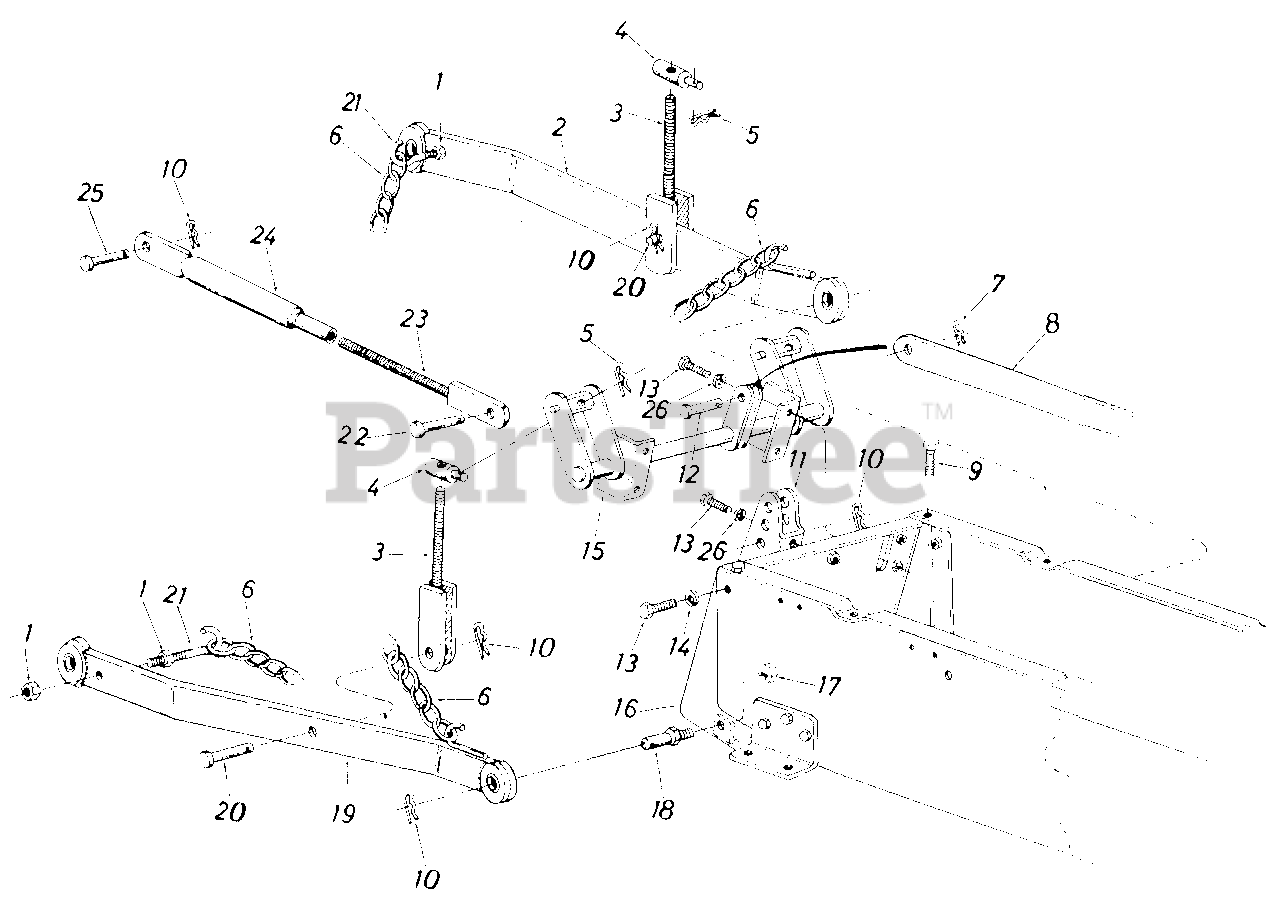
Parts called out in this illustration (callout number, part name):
1	Hex Cent. L-Nut 7/16-14 Thd.
2	Draft Bar Ass'y.-L.H.
3	Clevis Screw Ass'y.
4	Clevis Pin
5	Hitch Pin Clip
6	Chain 20 Links
7	Cotter Pin 1/8" Dia. x 1.25" Lg.
10	Hairpin Cotter
12	Clevis Pin
13	Hex Scr. 3/8-16 x .75" Lg.
14	L-Wash. 3/8" Scr. H.D.
18	Link Clevis Pin
19	Draft Bar Ass'y.-R.H.
20	Clevis Pin .63 Dia. x 1.66" Lg.
21	Hitch Chain Hook
22	Clevis Pin .63 Dia. x 2.4" Lg.
23	Clevis Screw
25	Clevis Pin .63 Dia. x 2.4" Lg.
26	L-Wash. 3/8" Scr. H.D.
13196-0648	PLATE-HITCH - TECH GRAY (0648)
13196-0665	PLATE-HITCH - YARDMAN GREEN (0665)
